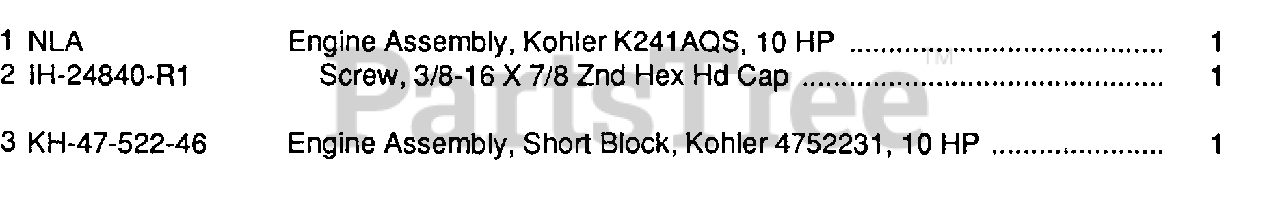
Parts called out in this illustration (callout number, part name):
1	Engine Assembly, Kohler K241AQS, 10 HP
2	Screw, 3/8 - 16 x 7/8 Znd Hex Hd Cap
3	Engine Assembly, Short Block, Kohler 4752231, 10 HP
